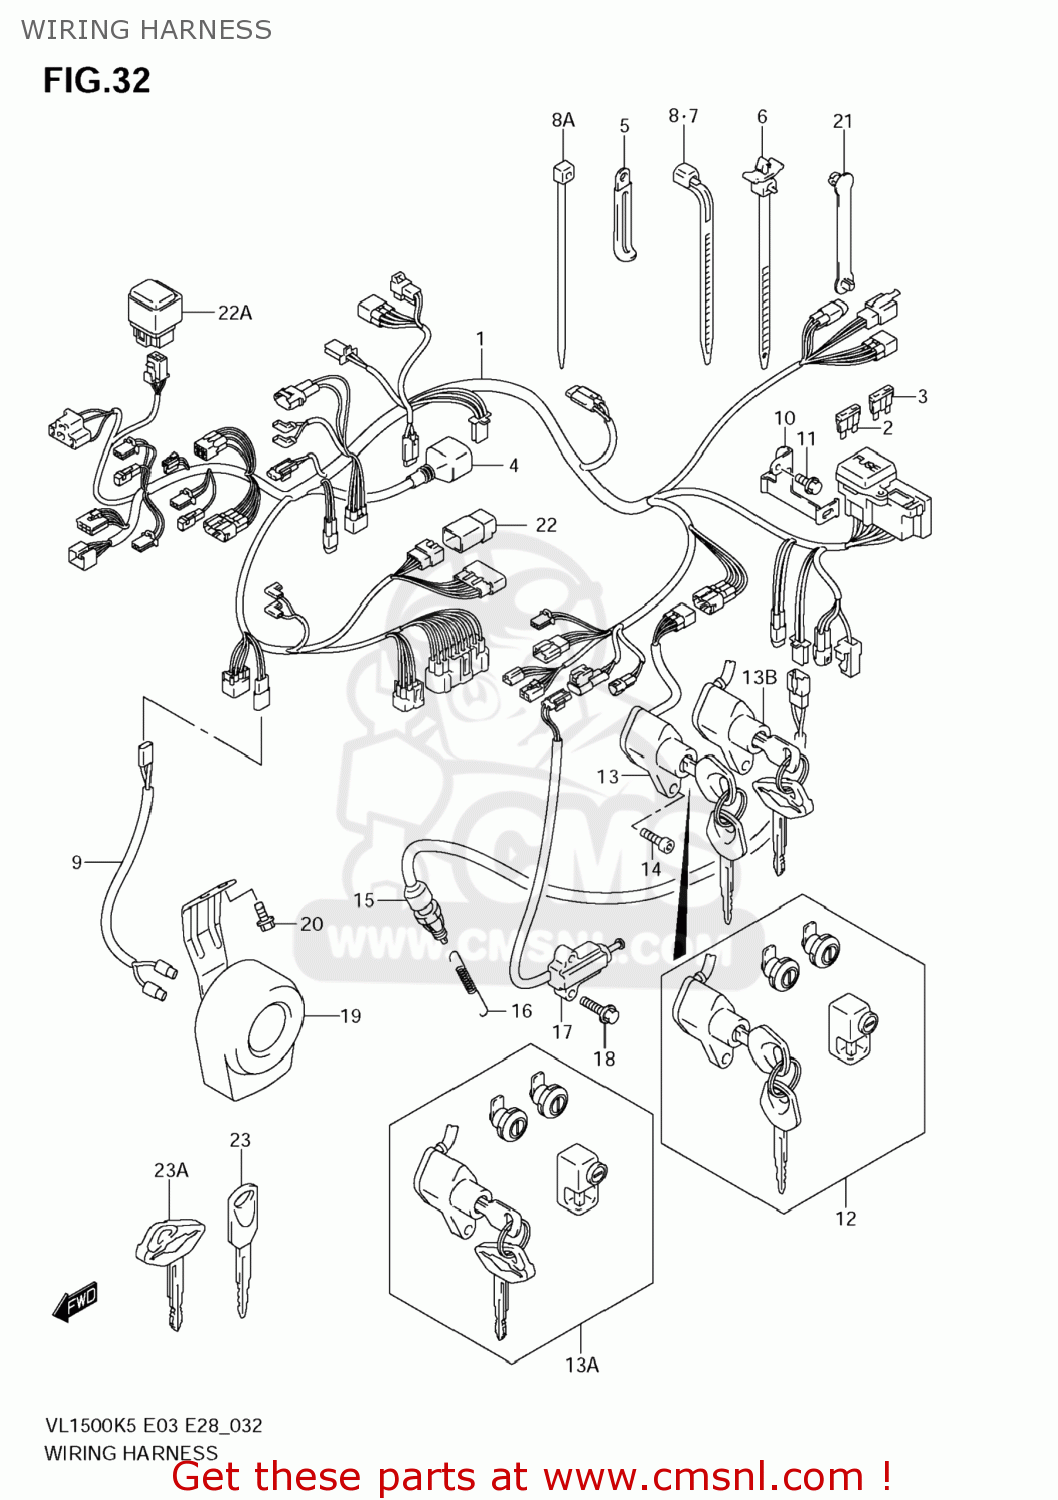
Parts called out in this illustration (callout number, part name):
1	HARNESS,WIRING
2	FUSE(10A)
3	FUSE(15A)
4	COVER,SPEEDOMETER COUPLER
5	CLAMP(L:45)
6	CLAMP(L:90)
7	CLAMP(L:125)
8	CLAMP(L:190)
8A	CLAMP(L:145)
9	WIRE,HORN LEAD
10	BRACKET,FUSE
11	BOLT
12	LOCK SET
13	SWITCH ASSY,IGNITION
13A	LOCK SET
13B	SWITCH ASSY,IGNITION
14	BOLT
15	SWITCH ASSY,STOP LAMP
16	SPRING,STOP LAMP SWITCH
17	SWITCH ASSY,SIDE STAND
18	BOLT
19	HORN ASSY
20	BOLT
21	CLAMP(L:33)
22	RELAY ASSY
22A	RELAY ASSY
23	KEY,BLANK
23A	KEY,BLANK(BOULEVARD)
